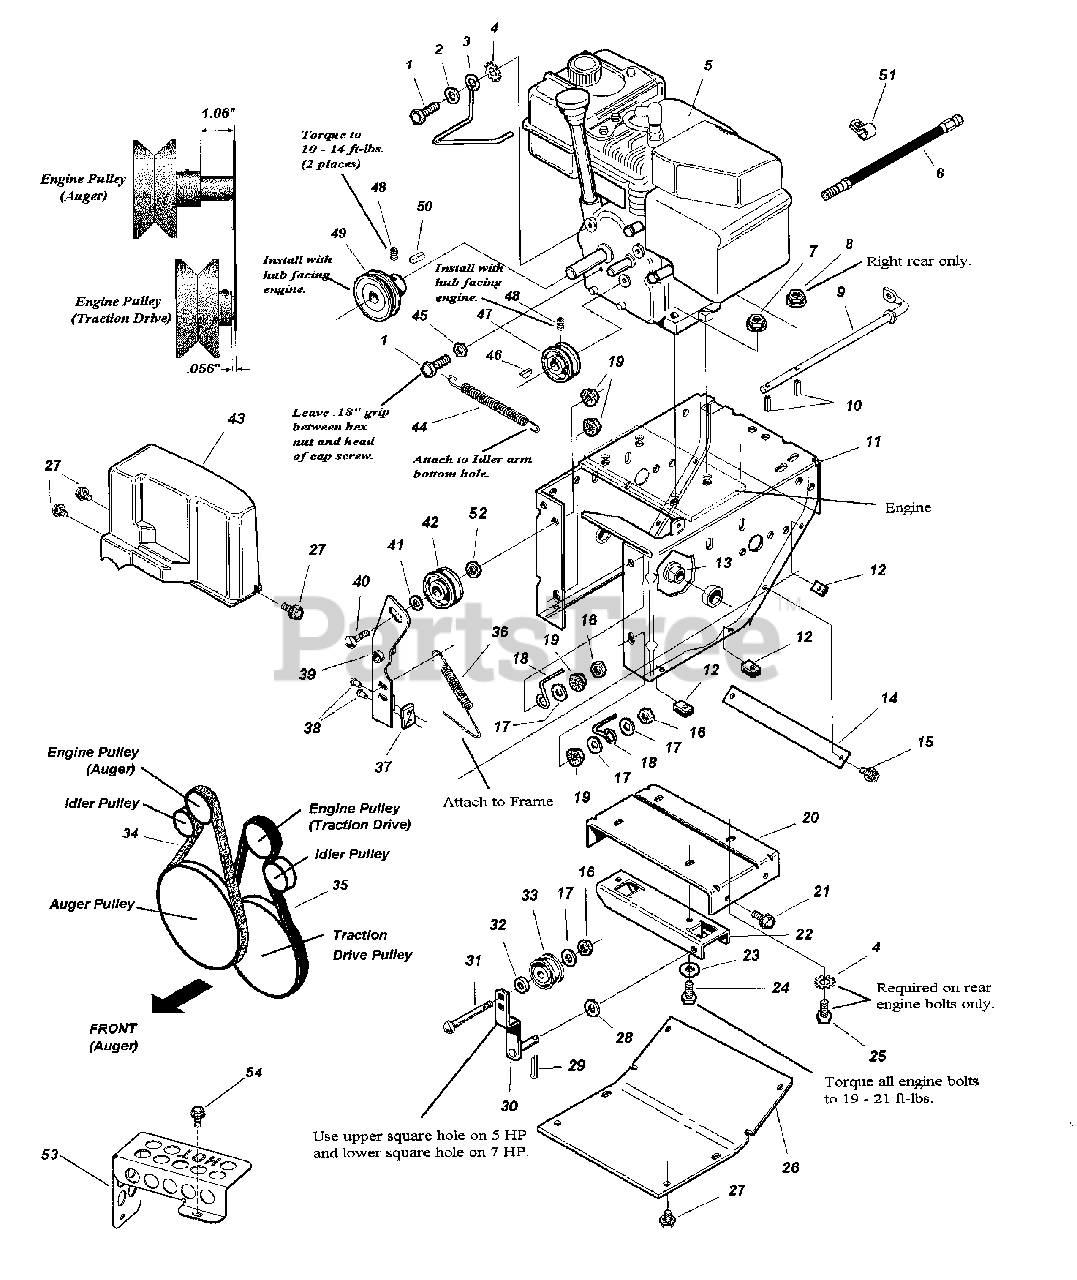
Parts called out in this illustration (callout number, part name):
1	SCREW, 5/16-24 x 3/4" Hex Head Cap, GR 5
2	WASHER, 5/16" Flat
3	WIRE, Belt Stop
4	LOCKWASHER, 5/16" Exterior Tooth
6	HOSE, Oil Drain
7	NUT, 5/16-18 Hex Flange Lock- small
8	NUT, 5/16-18 Hex Flange Lock
10	ROLL PIN, 3/16 x 3/4"
11	FRAME ASSEMBLY, Intermediate (Orange)
12	SPEED NUT, 1/4-20 U-Type
13	BUSHING, 1.00 long
14	SUPPORT, Tie Bar
15	SCREW, #10-24 x 1/2" Hex Washer Self-Tap
16	JAM NUT, 3/8-16 Hex Center Lock
17	WASHER, 3/8" Flat
18	ROD, Belt Guide
19	NUT, 3/8-16 Hex Nyloc Heavy Thin
20	SUPPORT, Frame
21	SCREW, 5/16-18 x 1/2" Hex Washer Self-Tap
22	SUPPORT, Pivot
23	WASHER, 5/16" Flat
24	SCREW, 5/16-18 x 1-3/4 Hex Head Cap, GR 5
25	SCREW, 5/16-18 x 1-3/4 Hex Head Cap, GR 5
26	COVER, Bottom, Orange
27	SCREW, 1/4-20 x 5/8" Hex Washer Self-Tap
28	WASHER, 7/16" Flat
29	COTTER PIN, 1/8 x 3/4"
30	IDLER ARM ASSEMBLY
31	BOLT, 3/8-16 x 1-1/4" Short Square Neck Carriage
32	SPACER, .377 ID x .75 OD x .312 Long
33	PULLEY, Idler
34	BELT, Auger Drive, V Groove
35	BELT, Traction Drive, V Groove
36	SPRING, Extension
38	RIVET, Blind
39	ASSEMBLY, Idler Arm w/Brake Pad
40	BOLT, 3/8-16 x 1-3/4 Short Square Neck Carriage, GR 5
41	WASHER, 3/8" Flat (.41 ID x 1.00 OD x .13 Thick)
42	PULLEY, Idler
43	COVER, Belt
44	SPRING, Idler- Extension
45	JAM NUT, 5/16-24 Hex
46	KEY - Hi Pro .125 x .625 HP 504 SAE1035
47	PULLEY, V Groove
48	SET SCREW, 5/16-18 x 5/16" Hex Recess, Cup Point
49	PULLEY, 2.75 OD
50	KEY, 3/16 Square x 1"
51	HARNESS CLIP
52	NUT, 3/8-16 Hex Flange Lock Two Way
53	MUFFLER GUARD, Domestic (Tecumseh)
54	SCREW, #10-24 x 5/8" Hex Washer Self-Tap
